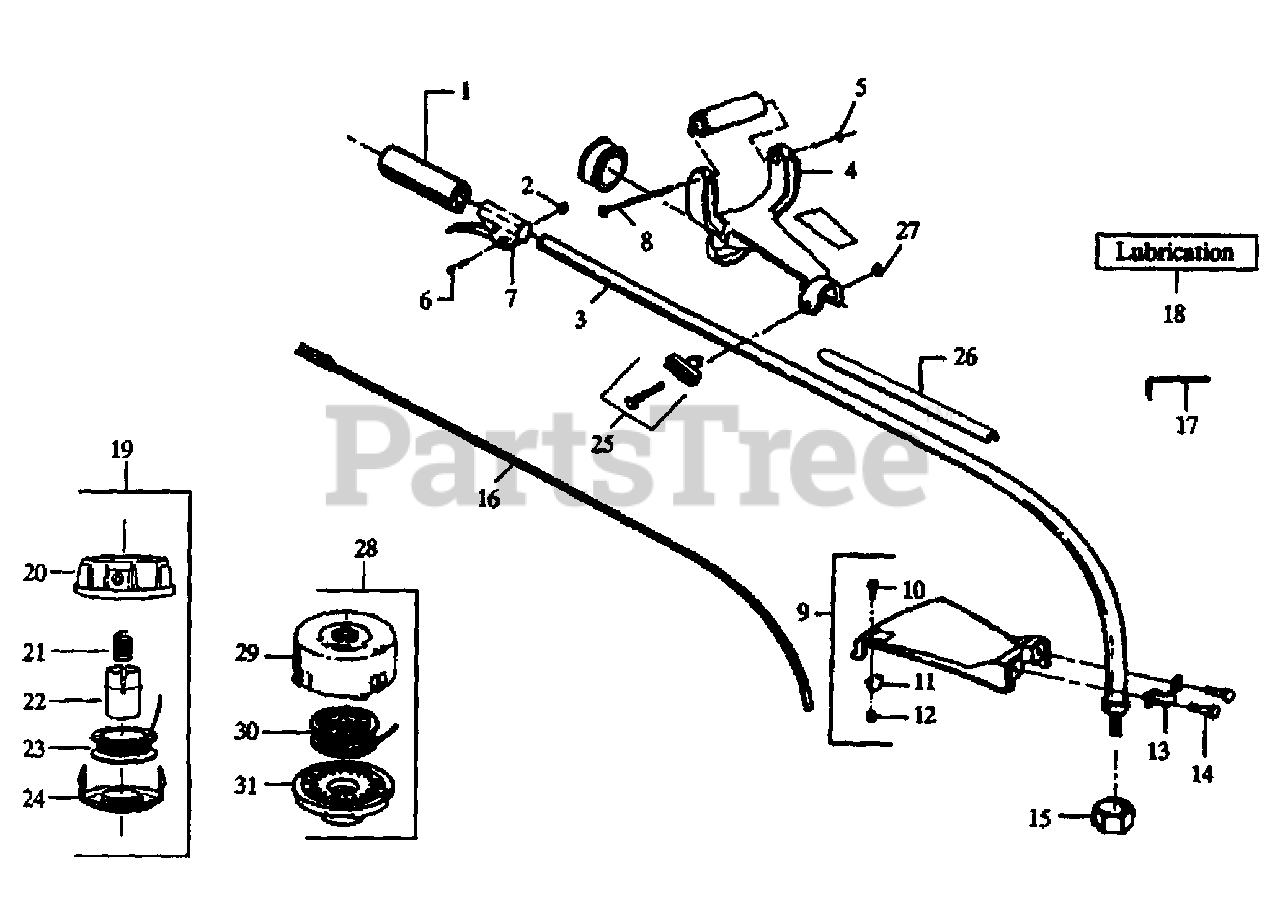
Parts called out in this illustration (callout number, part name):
3	Drive Shaft Housing
4	Antivibe Handle
7	Throttle Housing Ass'y.
9	Shield Kit Ass'y.
11	Line Limiter
12	Locknut
13	Shield Bracket
14	Screw
16	Drive Shaft
17	Hex Wrench (5/32)
18	Shaft Lubrication
19	Cutting Head Ass'y.
20	Hub Ass'y.
22	Release Button
23	Spool w/Line
25	"T" Handle
26	Shaft Warning Decal
28	Cutting Head Ass'y.
29	Hub Ass'y.
30	Spool w/Line
